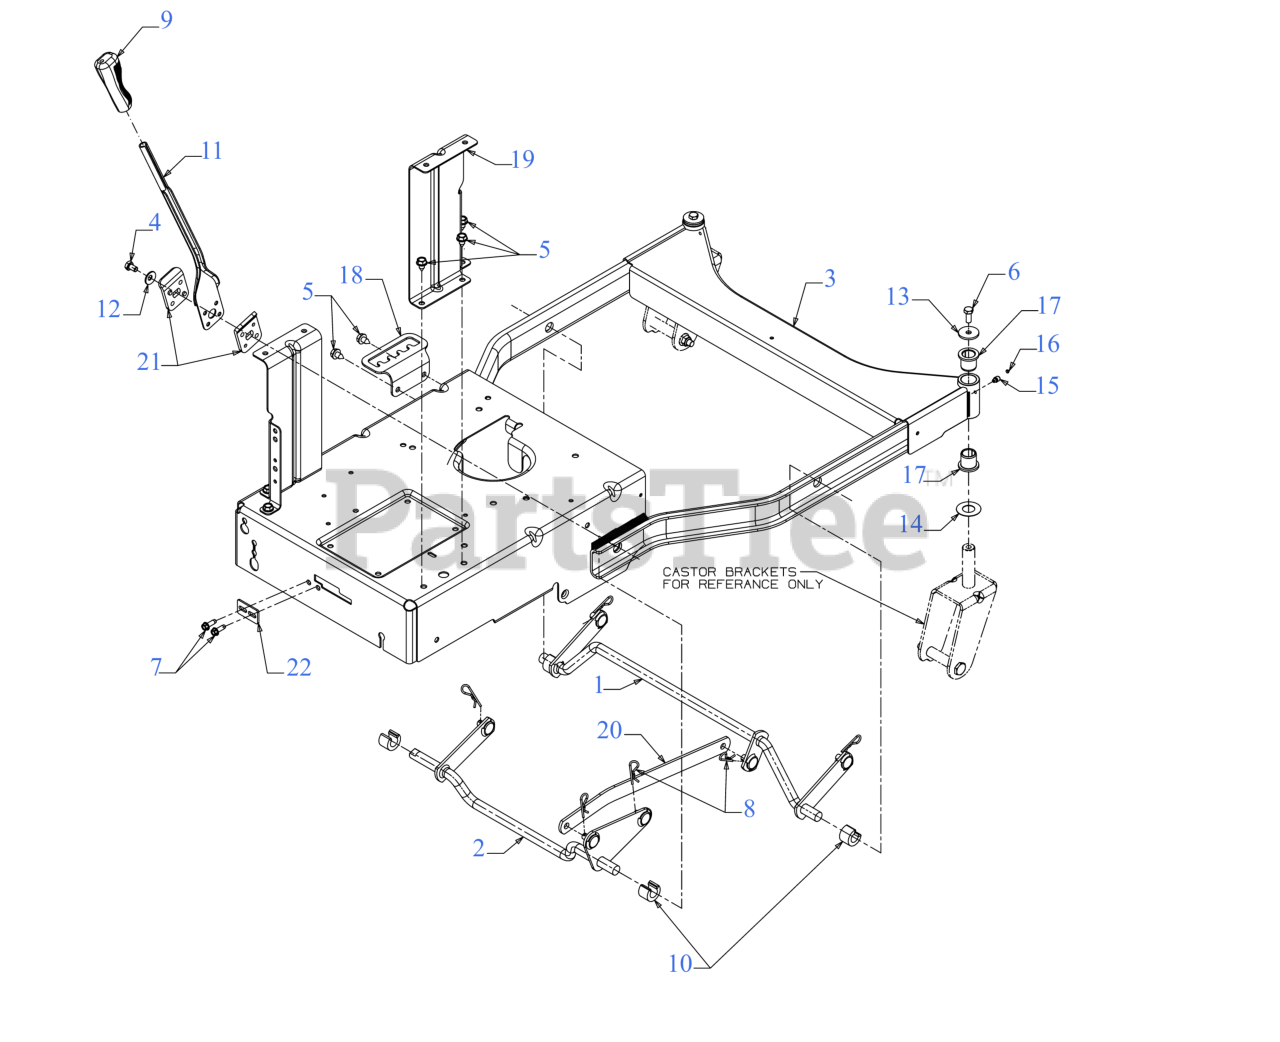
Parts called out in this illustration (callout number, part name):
1	FRONT LIFT ASSEMBLY(POWDER BLACK)
2	DECK LIFT ASSEMBLY (POWDER BLACK)
4	SCREW 5/16-18 x .50
5	SCREW 5/16-18 x .625
6	SCREW 5/16-24 x .750 GR5
7	SCREW 1/4-20 x .750
8	INTERNAL COTTER PIN
9	HANDLE GRIP
10	SNAP SPACER
11	DECK HEIGHT LEVER
12	BELL WASHER .337 X.867 x .057
13	WASHER-5/16 x 1.25X 1.27
14	THRUST WASHER
15	GREASE FITTING
17	FLANGE BEARING .760 ID
21	HEIGHT LEVER BRACKET
22	SHIFT PLATE
